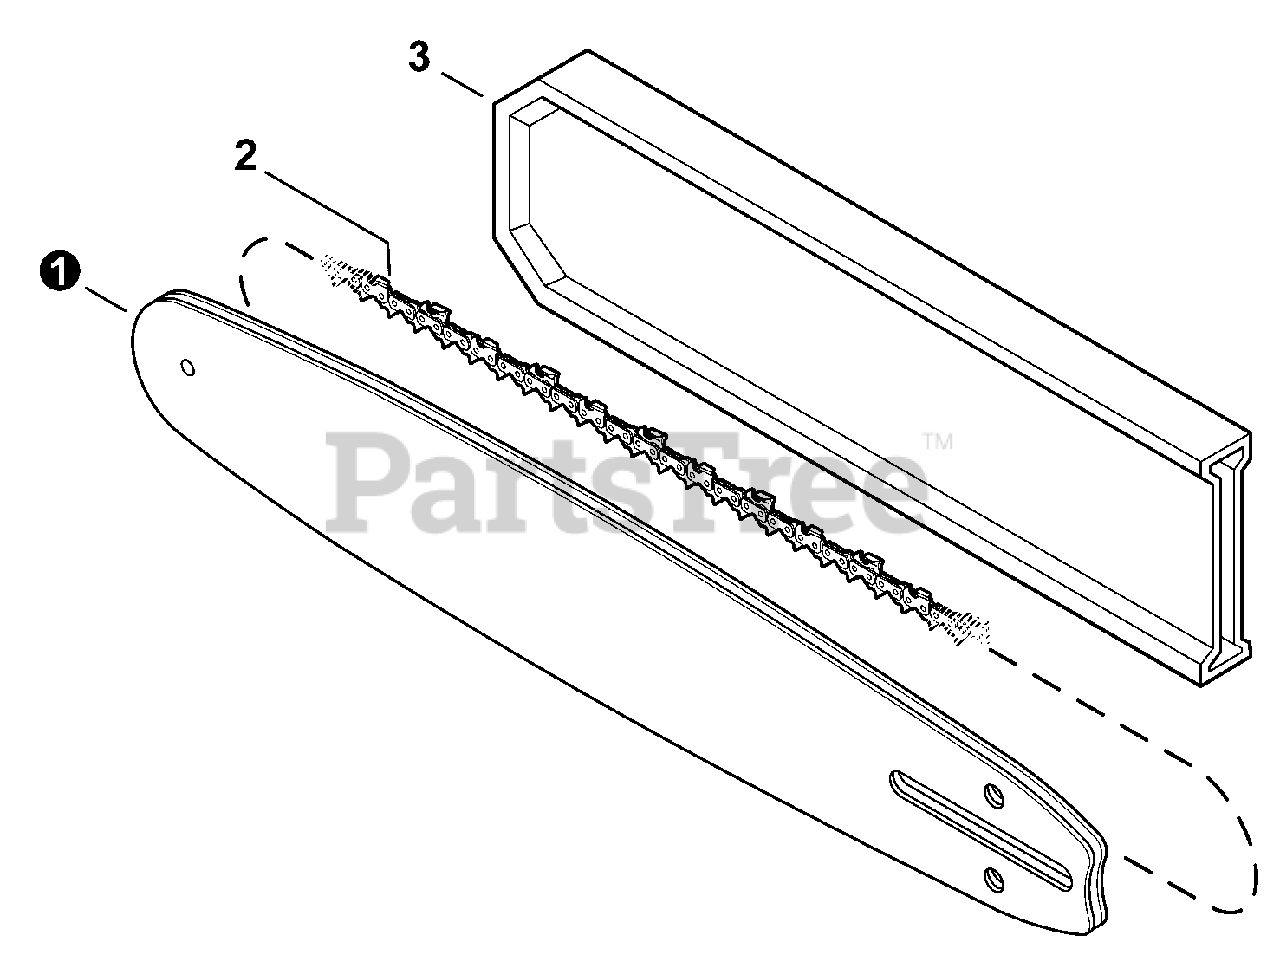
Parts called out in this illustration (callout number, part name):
1	GUIDE BAR, 10" 0.050" GA
1	GUIDE BAR, 10" 0.043" GA
1	GUIDE BAR, 12" 0.050" GA
1	GUIDE BAR, 12" 0.043" GA
2	SAW CHAIN 10" 0.050" GA
2	SAW CHAIN 10" 0.043" GA
2	SAW CHAIN 12" 0.050" GA
2	SAW CHAIN 12" 0.043" GA
3	SCABBARD 12"
3	SCABBARD 10"
